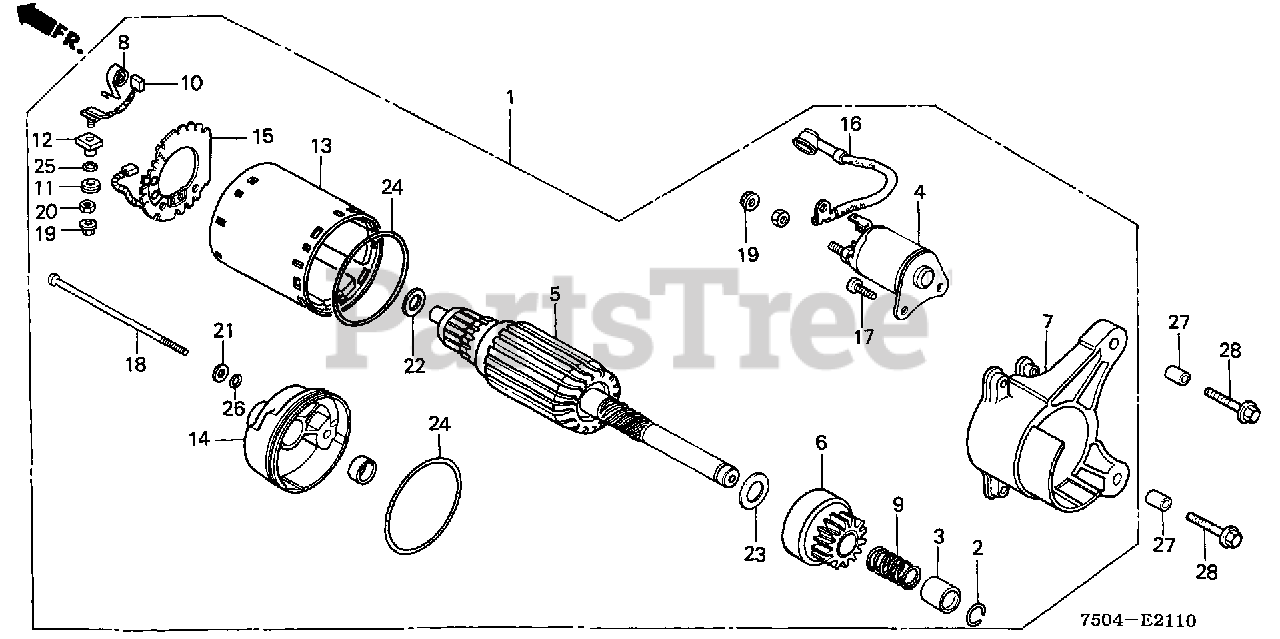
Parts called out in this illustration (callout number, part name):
1	MOTOR ASSY., STARTER
2	RING, SNAP
3	COLLAR, CLUTCH
4	CONTACTOR ASSY.
6	CLUTCH, OVERRUNNING
7	HOUSING, DRIVE SIDE
8	SPRING, BRUSH
11	BUSHING, INSULATION
12	BUSHING, INSULATION
14	FRAME, STARTER END
15	PLATE, BRUSH HOLDER
16	WIRE, WATER COVER
16	WIRE, WATER COVER (NOT AVAILABLE)
17	BOLT
18	BOLT, THROUGH (NOT AVAILABLE)
21	WASHER, STEEL PLATE
22	WASHER
27	PIN A, DOWEL (10X16)
28	BOLT, FLANGE (8X40)
